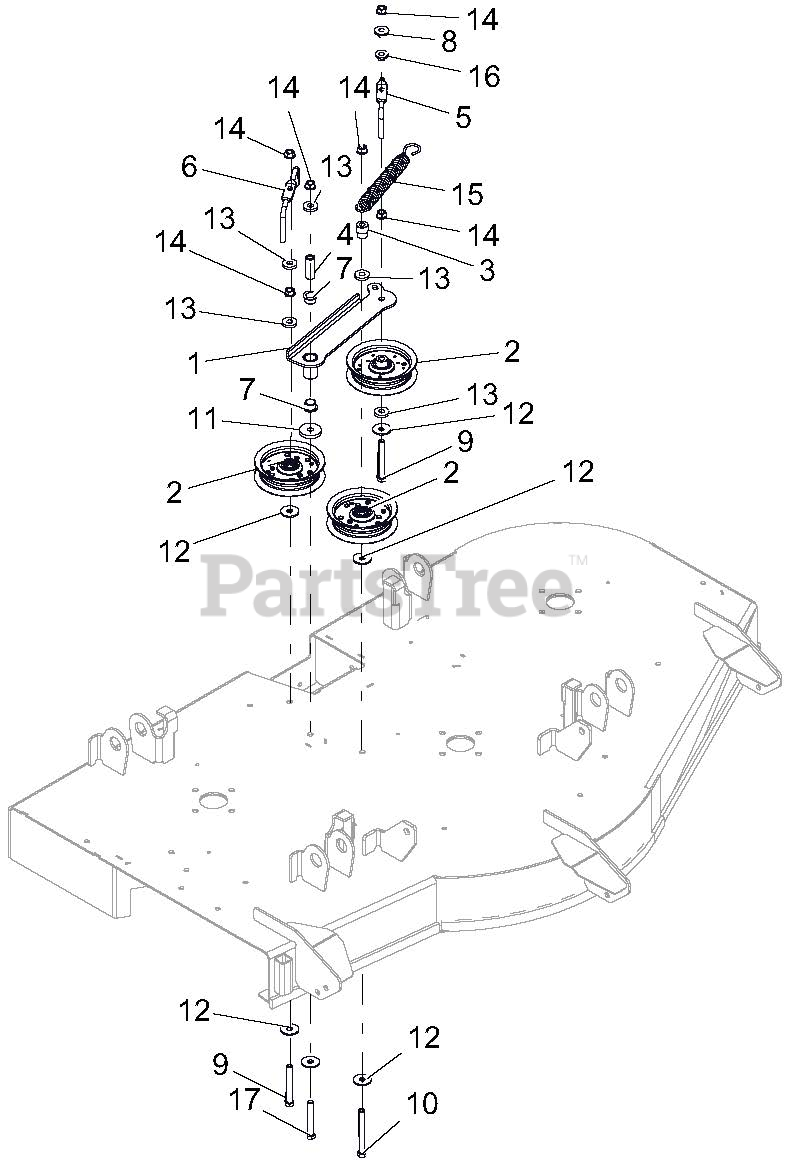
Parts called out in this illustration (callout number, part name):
1	WLDMT, IDLER - 52" IDLER ARM
2	ASM, IDLER 4"
3	BUSHING, IDLER
4	SPCR, .375IDX.625ODX1.66 PM
5	WIREFORM, BELT FINGER
6	FINGER, BELT
7	BSHG, FLANGE .625 x .75 x .50 x 1.00
8	BSHG-FLG .385X.500X.8751X.3
9	BLT-HEX .38-16X3.00 GR5 FTH YWZC
10	BLT-HEX .38-16X3.50 GR5 YWZC
11	WSHR-FL-STL .406X1.50X.245 YWZC
12	WSHR-FL-STL .406X1.25X.10 YWZC
13	WSHR-FL-STL .406X1.00X.188 YWZC
14	NUT, LK-TOP-FLG .38-16 YWZC
15	SPRG, EXTENSION
16	BSHG, FLG .385 X .500 X .875 X .406
17	BLT-HEX .38-16X2.75 GR5 YWZC
